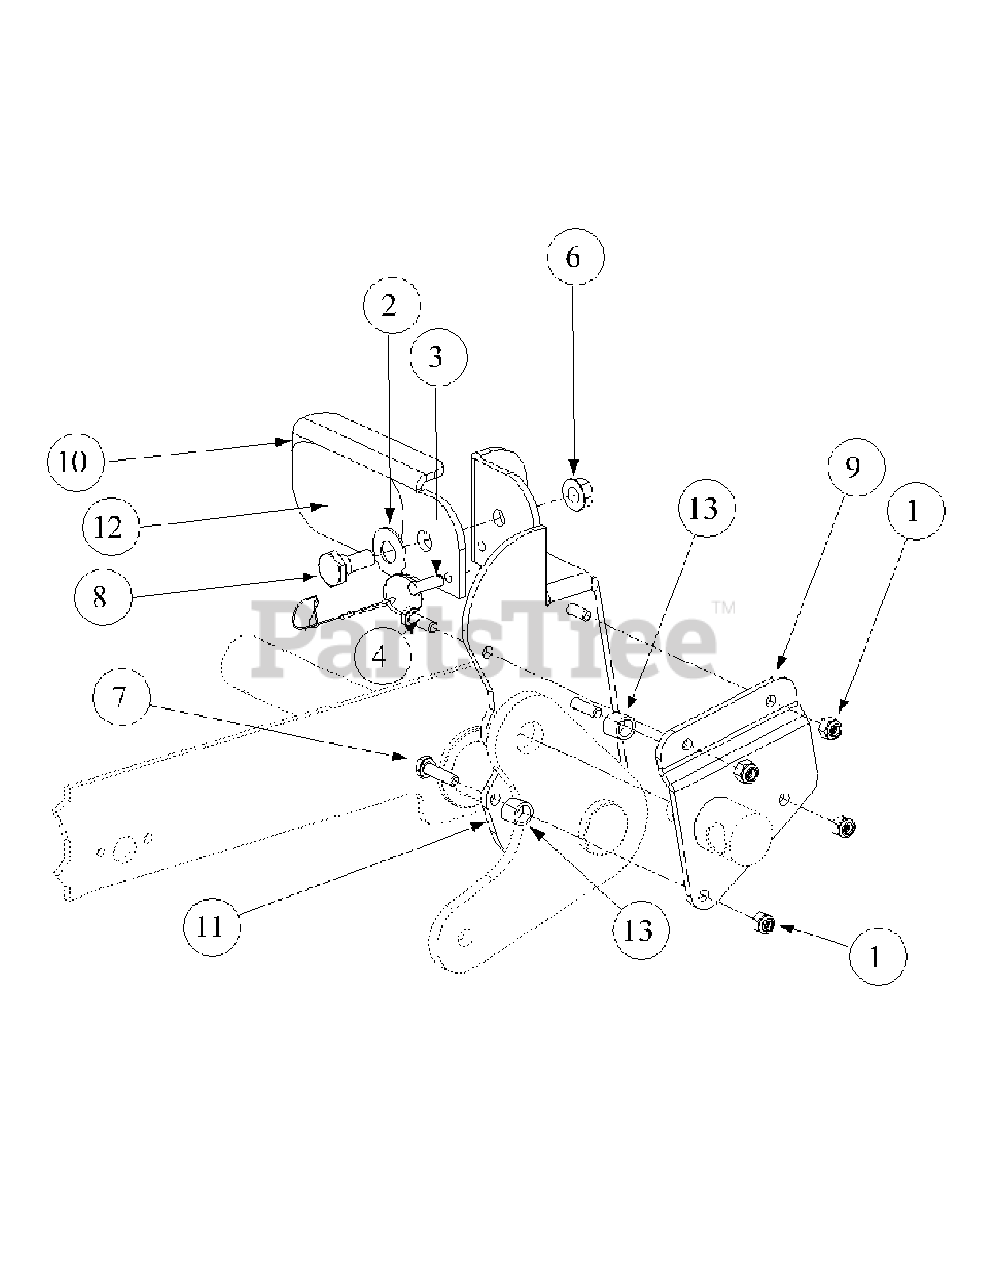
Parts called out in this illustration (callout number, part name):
1	Lock Nut, Nylon Insert, 1/4-20
2	Washer, 1/2 x 1 Shim
3	Detent Pin w/12" Lanyard
4	Hex Cap Screw, 1/4-20, .75
6	Hex Nut, Flange Lock 3/8-16
7	Hex Cap Screw, 1/4-20, 1.00
8	Shoulder Screw, .50 x .27 Lg., 3/8-16 1
9	Foot Lift Backup Pedal
10	Deck Foot Pedal Lift
11	Deck Foot Pedal Lift
12	Deck Foot Lift Pad
13	Turnbuckle Sleeve
